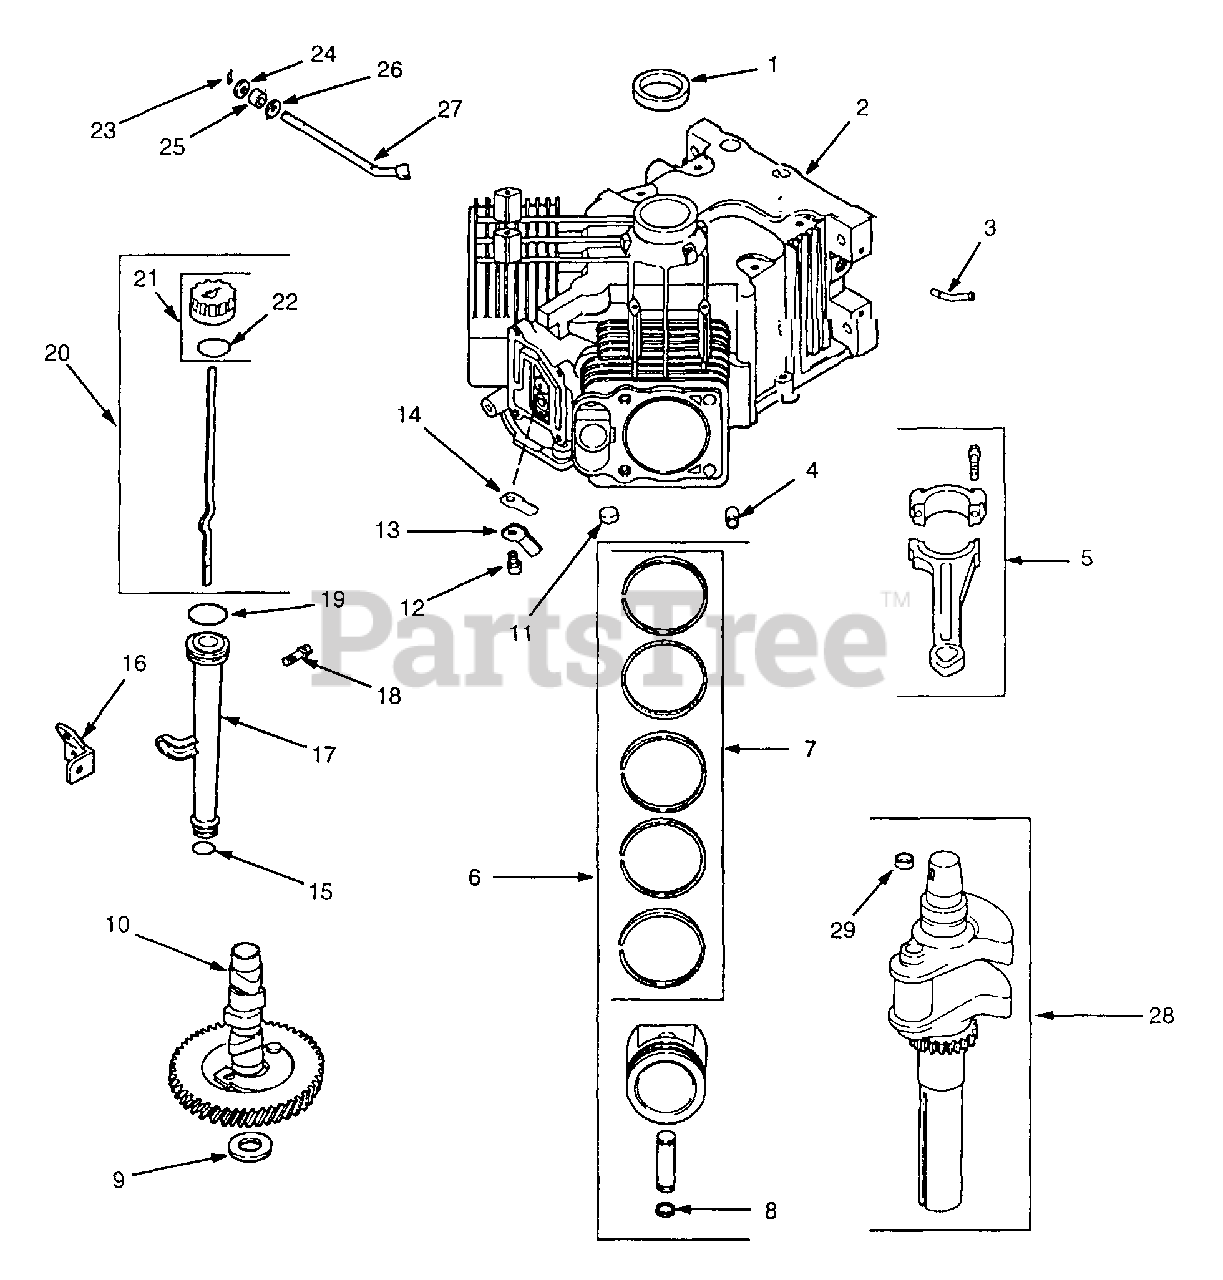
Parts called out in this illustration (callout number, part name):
1	Seal, Front Oil
2	Cylinder Block
4	Pin, Locating Dowel
5	Rod Ass'y, Connecting, Std
6	Piston w/Ring Set, Std
7	Ring Set, Std
8	Retainer, Piston Pin
9	Shim, Crankshaft, .032 (Red)
10	Camshaft
11	Plug, Cup
12	Screw, Breather Reed Retainer M5 x 0.8 x 10
13	Retainer, Reed
14	Reed, Breather
15	O-Ring, Lower Oil Fill Tube
16	Bracket, Oil Fill Tube
17	Tube, Oil Fill
18	Screw, Hex Flange, M5 x 0.8 x 16
19	O-Ring, Upper Oil Fill Tube
20	Dipstick Ass'y
21	Kit, Oil Fill Cap
22	O-Ring, Dipstick
24	Washer, 6mm
25	Seal, Governor Cross Shaft
26	Washer, 1/4
27	Shaft, Governor Cross
28	Crankshaft
29	Plug, Cup
